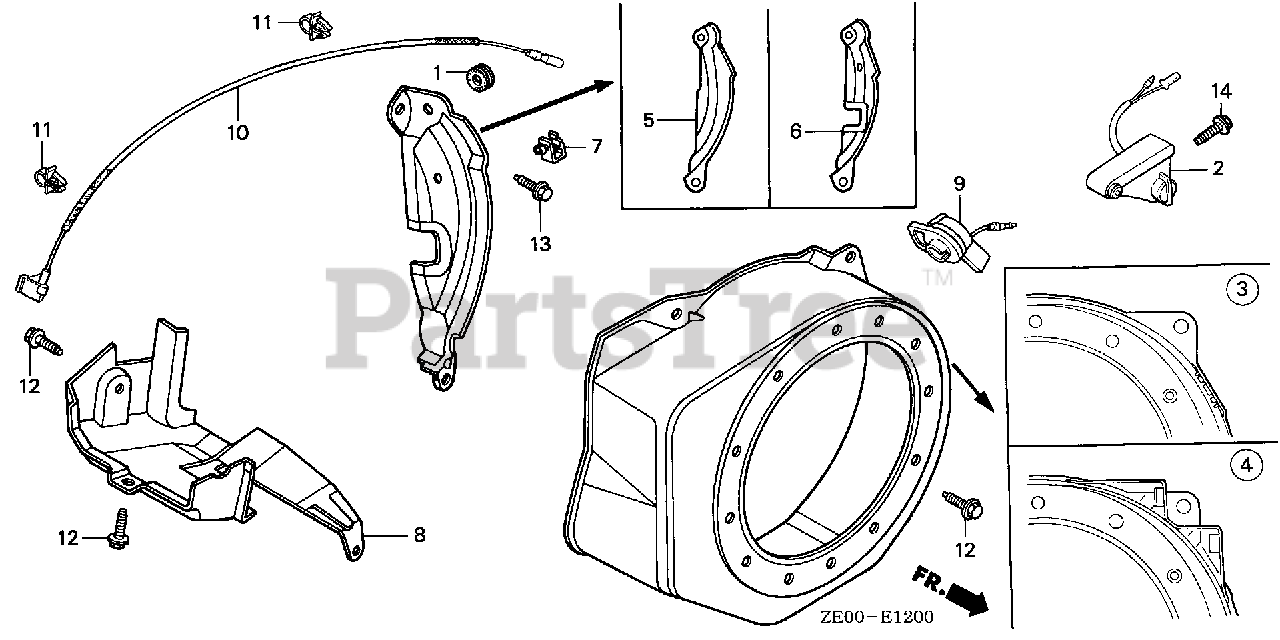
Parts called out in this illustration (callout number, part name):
1	GROMMET, ADJUSTING COVER
3	COVER, FAN *R8* (BRIGHT RED)
3	COVER, FAN *R280* (POWER RED)
5	PLATE, SIDE (STD)
8	SHROUD (NOT AVAILABLE)
9	SWITCH ASSY., ENGINE STOP
10	WIRE, STOP SWITCH (370MM)
11	HOLDER, STOP SWITCH WIRE
12	BOLT, FLANGE (6X12) (CT200)
13	BOLT, FLANGE (6X12) (CT200)
13	BOLT, FLANGE (6X20) (CT200)
